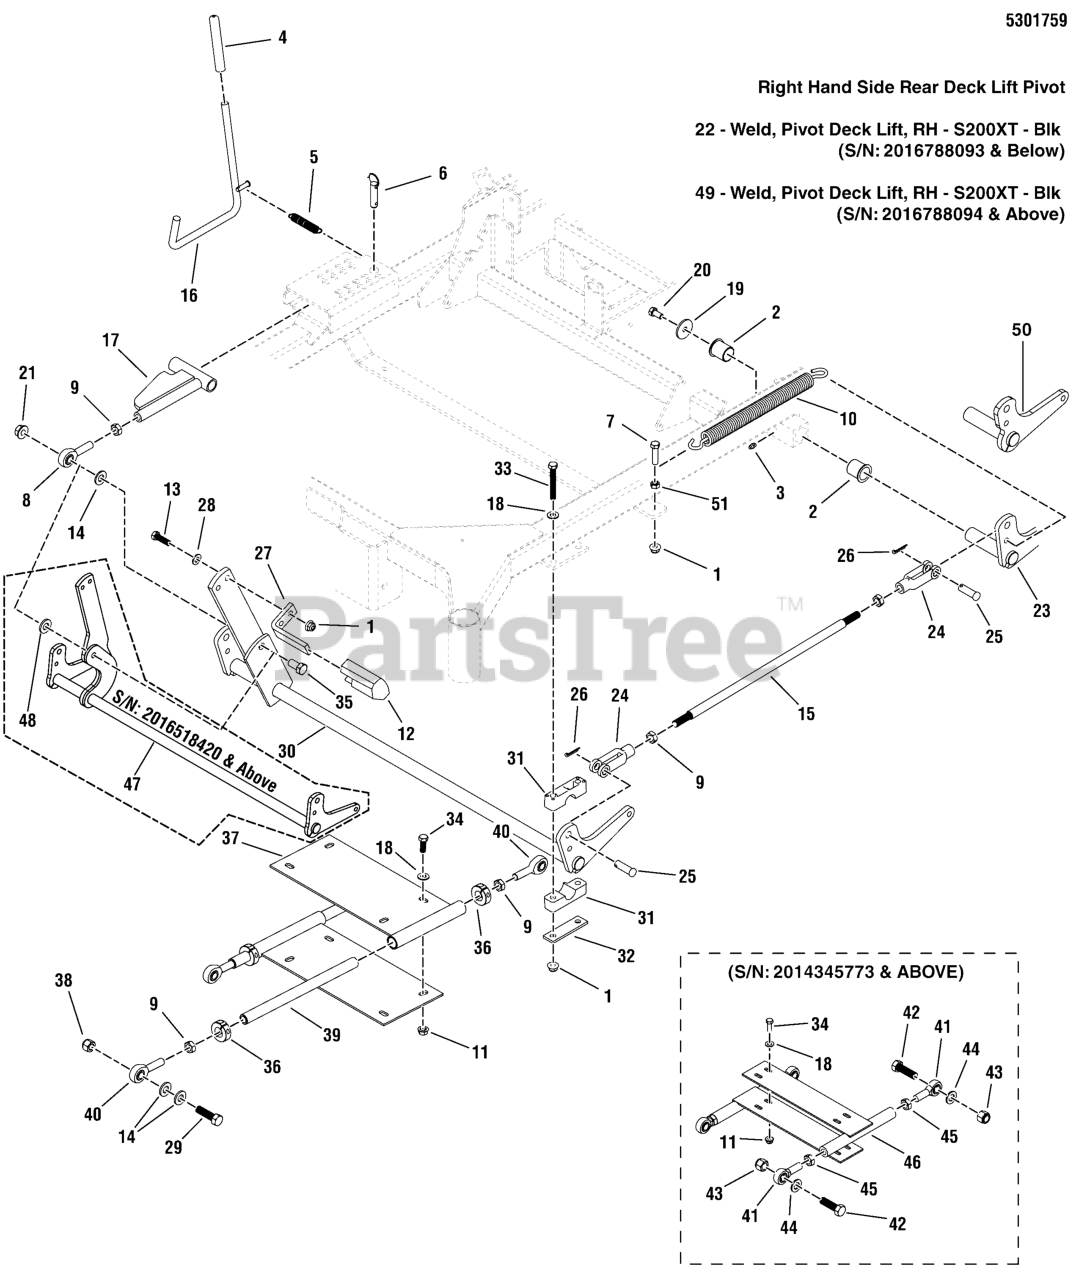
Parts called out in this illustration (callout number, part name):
1	NUT, 3/8 - 16 HEX NYLOCK FLANGE
2	BUSHING, 1.00 X 1.13 X 1.38, Plastic
3	GREASE FITTING, 1/4-28 Straight
4	GRIP, FOAM, .475 X 4.35 X .095
5	SPRING-EXT, .500 OD X 3.50 LG X .058 WR
6	PIN, HITCH, 1/2 X 2.00 OAL, YP
7	BOLT, 3/8-16 X 1-1/2" GD5 CZ
8	BALL JOINT, 1/2-20, MALE
9	NUT, 1/2-20 Hex Jam
10	SPRING-EXT, 1.00 ODX13.25LGX.177WR, BLK
11	NUT, 3/8-16 Hex Large Serrated Flange
12	PEDAL, Rubber
13	BOLT, 3/8-16 X 1-1/4" GD5 CZ
14	WASHER, 1/2 SAE
15	ROD, DECK LIFT, 19.25, CZ
16	WELD, ROD DECK LIFT - BLK
17	WELD, DECK ADJUST LINK - SNP RED
18	WASHER, 3/8 SAE
19	WASHER, .390 X 1.50 X .109, YZ
20	BOLT, 3/8-16 X 3/4, PLT W/PATCH
21	NUT, Hex Flange, Nylock, 1/2-13
22	WELD, PIVOT DECK LIFT, RH - S200XT - BLK
23	WELD, PIVOT DECK LIFT, LH - S200XT - BLK
24	CLEVIS, 1/2-20, STEEL, CLEAR ZINC
25	PIN, CLEVIS, 1/2 X 1-1/2, PLATED
26	* PIN, COTTER, 1/8" X 3/4
27	PEDAL, FOOT - BLK
28	WASHER, 3/8" GR. 9 FLAT
29	BOLT, 1/2-20 X 1-3/4" GD8 CZ
30	WELD, DECK LIFT SHAFT, S200XT - RED
31	PIVOT BLOCK, PLASTIC
32	PLATE, PIVOT BLOCK SUPPORT - BLK
33	BOLT, 3/8-16 X 2-3/4" GD5 CZ
34	BOLT, 3/8-16 X 1" GD5 CZ
35	BOLT, 1/2-13 X 2-1/4" GD5 CZ
36	COLLAR, 3/4" Split
37	WELD, DECK STABILIZER - BLK
38	NUT, Hex, Nylon Lock, 1/2-20
39	SHAFT, DECK STABILIZER
40	BALL JOINT, 1/2" MALE, EXTRA CAPACITY
41	BALL JOINT, 3/4-16, MALE
42	BOLT, 3/4-16 X 2-1/2" YZ GD5
43	NUT, Hex, Nylon Lock, 3/4-16
44	WASHER, 3/4 SAE
45	NUT, Hex, Jam, 3/4-16
46	WELD, DECK STABILIZER, IS2500Z-246 - BLK
47	WELD, DECK LIFT, 200XT-61 - RED
48	SPACER, .52 X 1.00 X .22, PM, CZ
49	WELD, PIVOT, DECK LIFT, LH, 200XT - BLK
50	WELD, PIVOT, DECK LIFT, LH - 200XT - BLK
51	NUT, 3/8-16 HEX JAM
